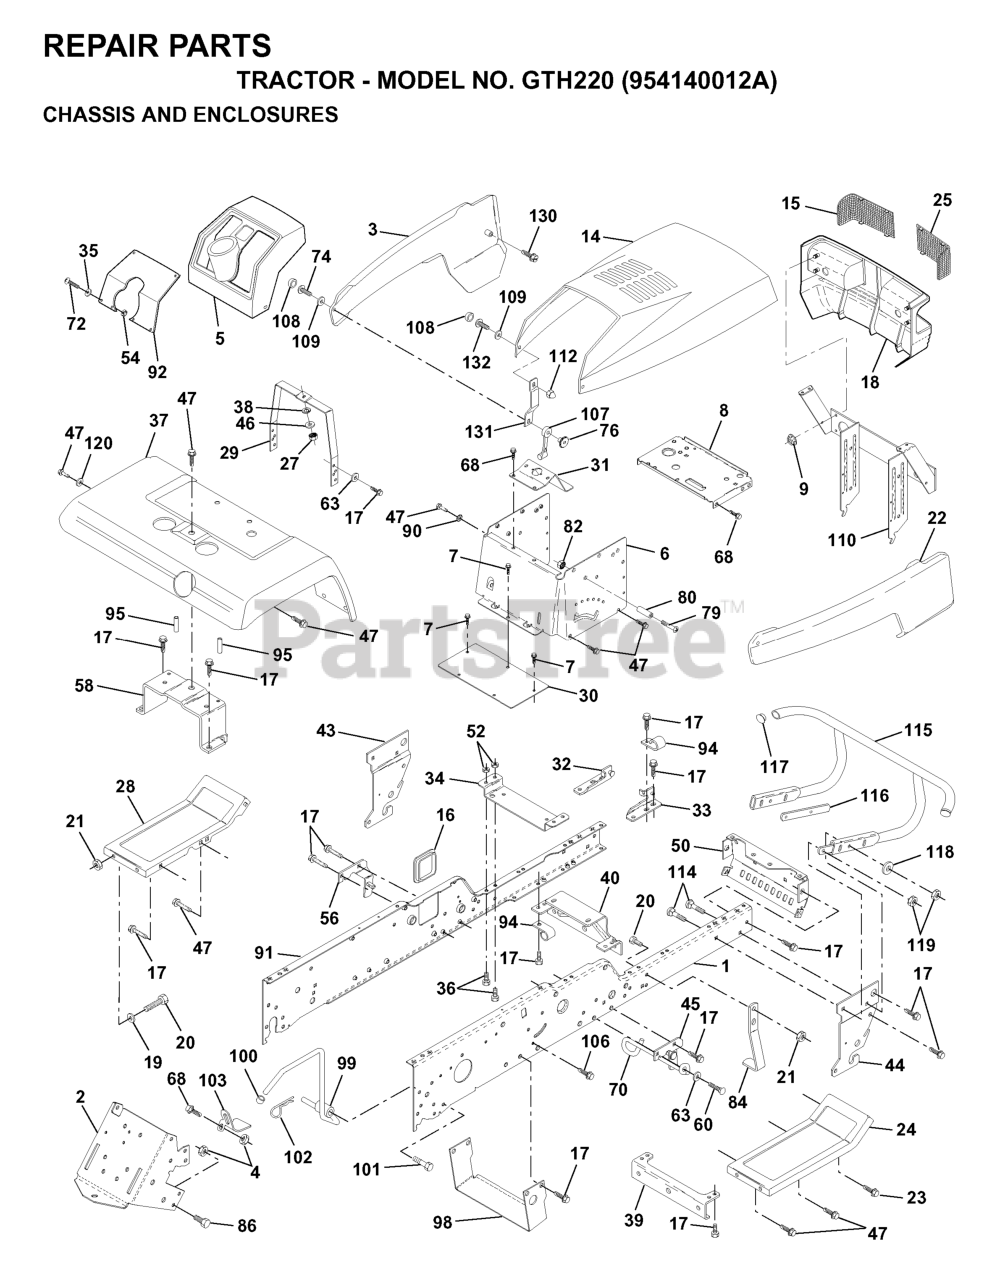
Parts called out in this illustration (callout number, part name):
1	RAIL, FRAME RH
2	DRAWBAR-GT
3	SIDE PANEL LH
4	Nut, Lock Hex 7/16 Unc
6	DASH ASS'Y LOWER
7	SCREW
8	SUPPORT, BATTERY
9	PAL NUT LT
14	HOOD ASM PNT
16	COVER ACCESS
17	SCREW
18	GRILLE.ASM.HUSQVARNA.YTGT
19	WASHER
20	BOLT
22	PANEL ASM SD RH
23	SCREW GTV
24	FOOTREST RH
25	LENS.RH.HUSQVARNA.YTGT.CL
27	NUT
28	FOOT REST LH
29	DASH SUPT YP
30	SADDLE.HYDRO.95
31	BRACE, SUPPORT STEERING
32	FRAME PIVOT BRKT ASSY LH
33	FRAME PIVOT BRKT ASSY RH
34	ENGINE SUPPORT BRKT
35	WASHER
36	BOLT.FIN.HEX.5/16-18X3/4
37	FENDER
38	LOCKWASHER
39	FRONT AXLE BRACKET
40	AXLE SUPPORT BRKT
43	FRONT SUSPENSION BRKT LH
44	FRONT SUSPENSION BRKT RH
45	BRACKET SUSP RH
50	BRACKET, CHASSIS FRONT
52	NUT.71038.31-18.HEX.NYLOCK
54	NUT
56	BRACKET ASM, SUSP CHASSIS
58	FENDER BRKT
60	SCREW
63	WASHER
68	Screw 5/16-18 x 1/2 Hex, Self Tapping 5/16-18 x 1/2
70	BELT GUIDE
72	Screw, Machine, Truss Head 5/16-18 UNC x 3/4
74	SCREW
76	WELDNUT
79	RP SCREW
82	NUT **
84	MOWER STOP
86	BOLT
90	LOCKWASHER
92	DASH PLATE
95	NUT-PUSH YT
98	BRACKET CHASSIS
99	ROD ASMBLY BYPASS
100	CAP
101	SCREW LT
102	RETAINER M
103	BRACKET LOCK BYPASS
106	SCREW
107	LATCH.HOOD.
108	SNAP CAP LT
110	PIVOT ASM GRL/HD
112	NUT
114	BOLT.3/8-14X1.25
116	BRACKET BUMPER
117	PLUG PLASTIC
118	WASHER
120	WASHER
130	Screw, SLTD Hex Hd. W/Pl Washer
131	BRACKET.SUPPORT.HOOD/PANEL.NLA
132	SCREW 10-24X3/8
